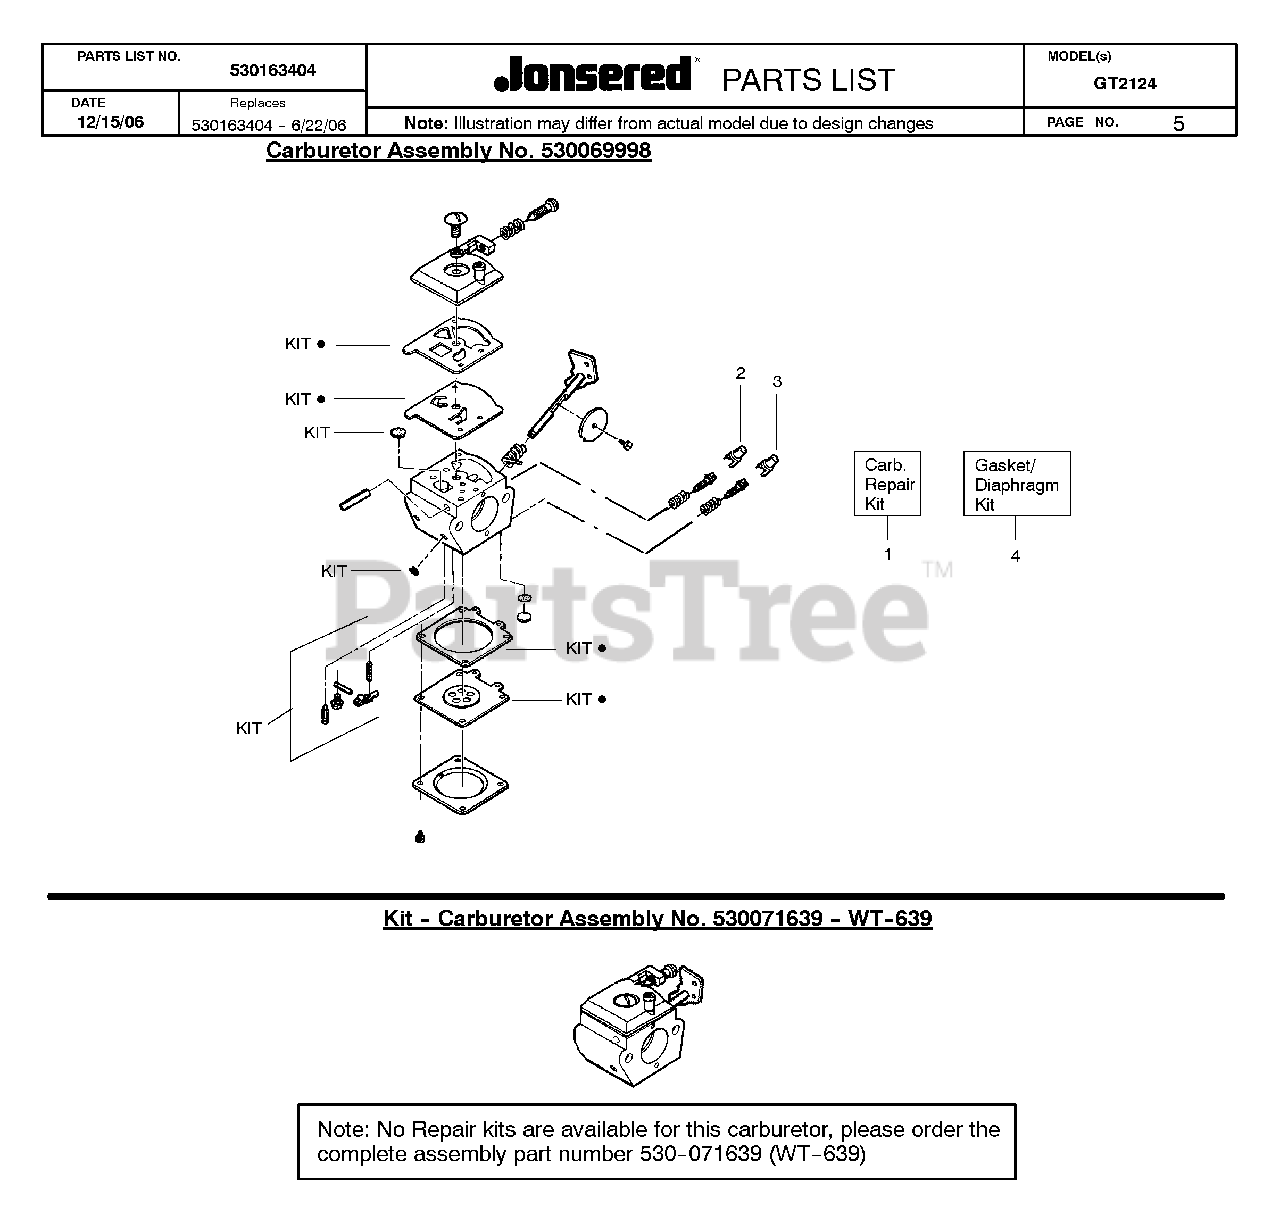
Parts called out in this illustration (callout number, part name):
1	CARB REPAIR KIT
2	LIMITER CAP-HIGH
3	LIMITER CAP-LOW
4	GASKET/DIAPHRAGM KIT
